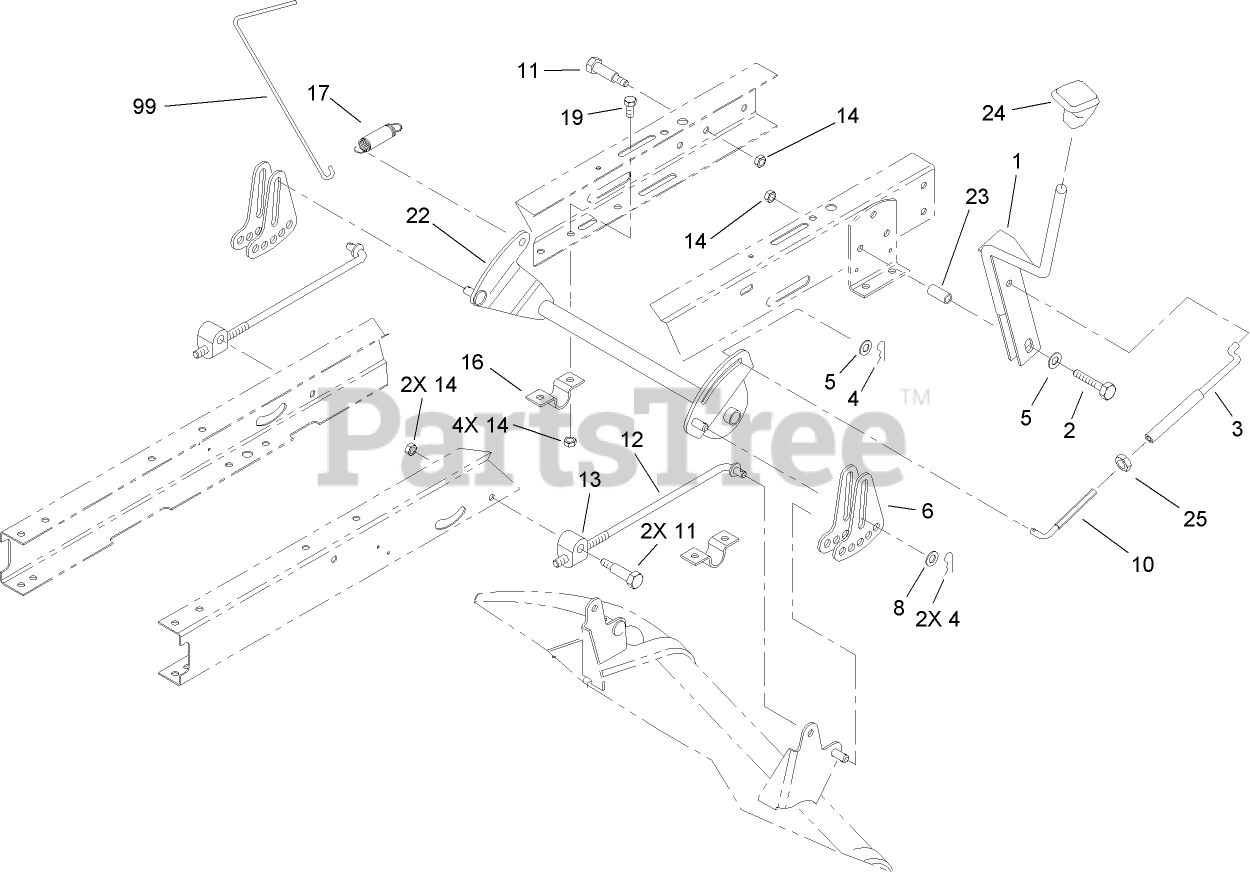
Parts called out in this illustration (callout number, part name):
2	SCREW-HH
3	HOC LINKAGE (WELDMENT)
5	WASHER-FLAT
6	LINK-ADJUSTING, HOC
8	WASHER-HARDENED
10	LINKAGE-HOC
11	SCREW-SHOULDER, HH
12	ROD-HANGER, REAR
13	TRUNNION-HOC
14	NUT-LOCK, NI
16	CLAMP-PIVOT, HOC
17	SPRING-EXTENSION
19	SCREW-HH
22	HOC PIVOT ASM (BLACK)
23	SPACER
24	KNOB-SHIFT
25	NUT-JAM
99	TOOL-SPRING
